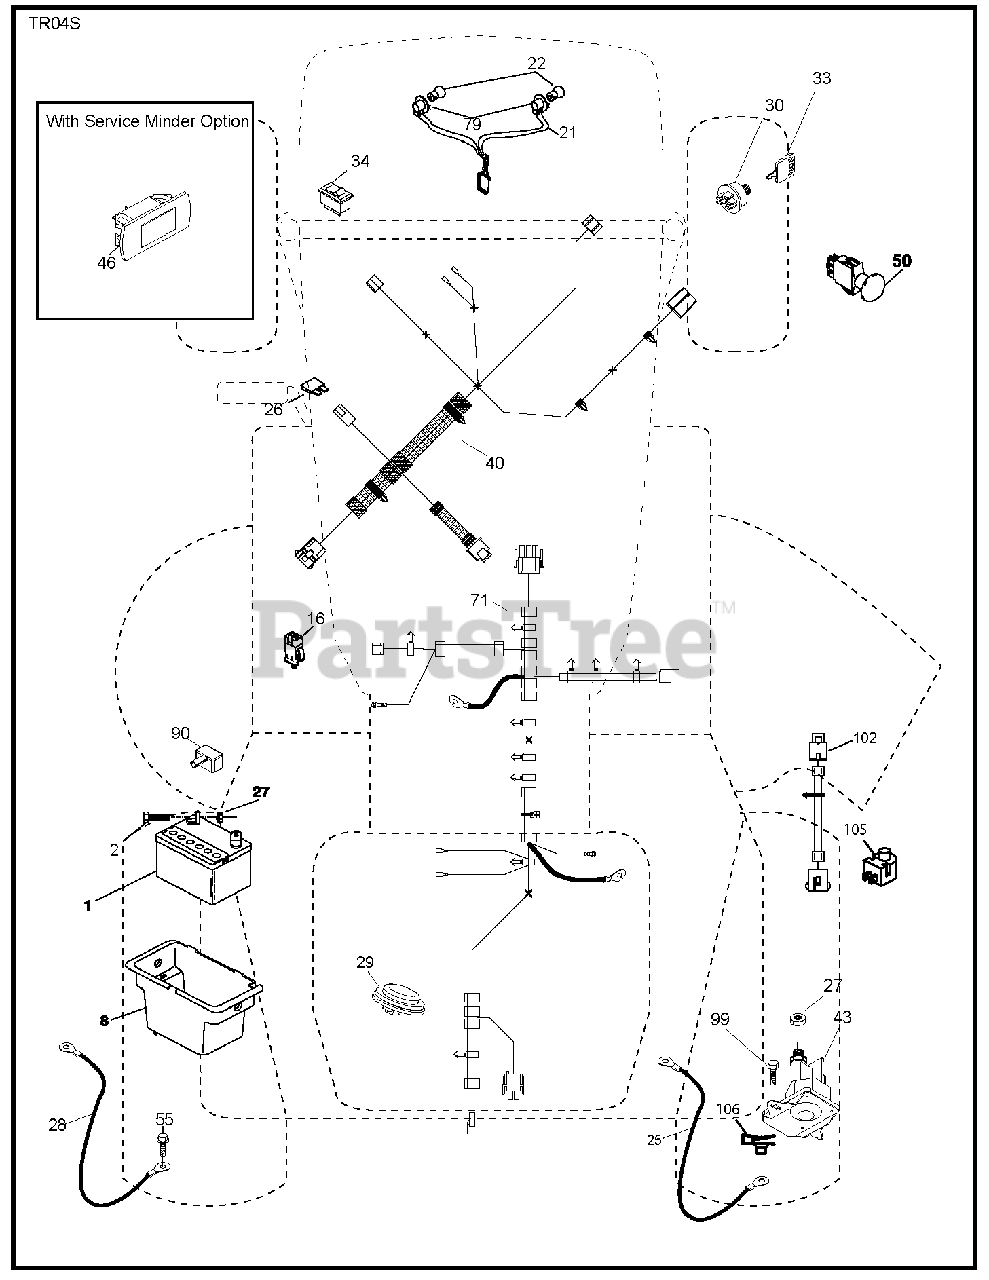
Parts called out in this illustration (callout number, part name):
1	Battery, Dry 30 Amp
2	BOLT.HEX.1/4.X.3/4.DICHROMATE
8	BOX.BATTERY.MNT.REAR.L
16	SWITCH INTERLOOK PUSH-IN
21	HARNESS.LIGHT W/4152J BULBS
25	CABLE.BATT.RED.8GA.17
26	FUSE 20AMP
27	NUT
28	CABLE.GROUND.REAR.BATTERY.8G
29	SWITCH.SEAT.DELTA.OPC.
30	SWITCH.IGN.DELTA.W.LGH.ROS
33	KEY.CHAIN.BLISTER.PACK.GEN.INT
40	HARNESS.TEX.DASH.ELEC.REAR BAT
43	SOLENOID.W/BRASS.PLUNGER
46	GUAGE.SRVCMNDR.HRMTR.
50	RB PTO.SWITCH.8 TERMINAL.BLACK
55	SCREW 5/16"
71	HARNESS.TEX.CHSSIS.REAR.BATT
79	BULB HOLDER ASM.
90	COVER.TERMINAL.BATTERY
99	SCREW HEXWSHR 1/4-20X3/4
102	HARNESS PIGTAIL PCH TEX ROS
105	REVERSE SWITCH
106	1/4-20 U NUT
